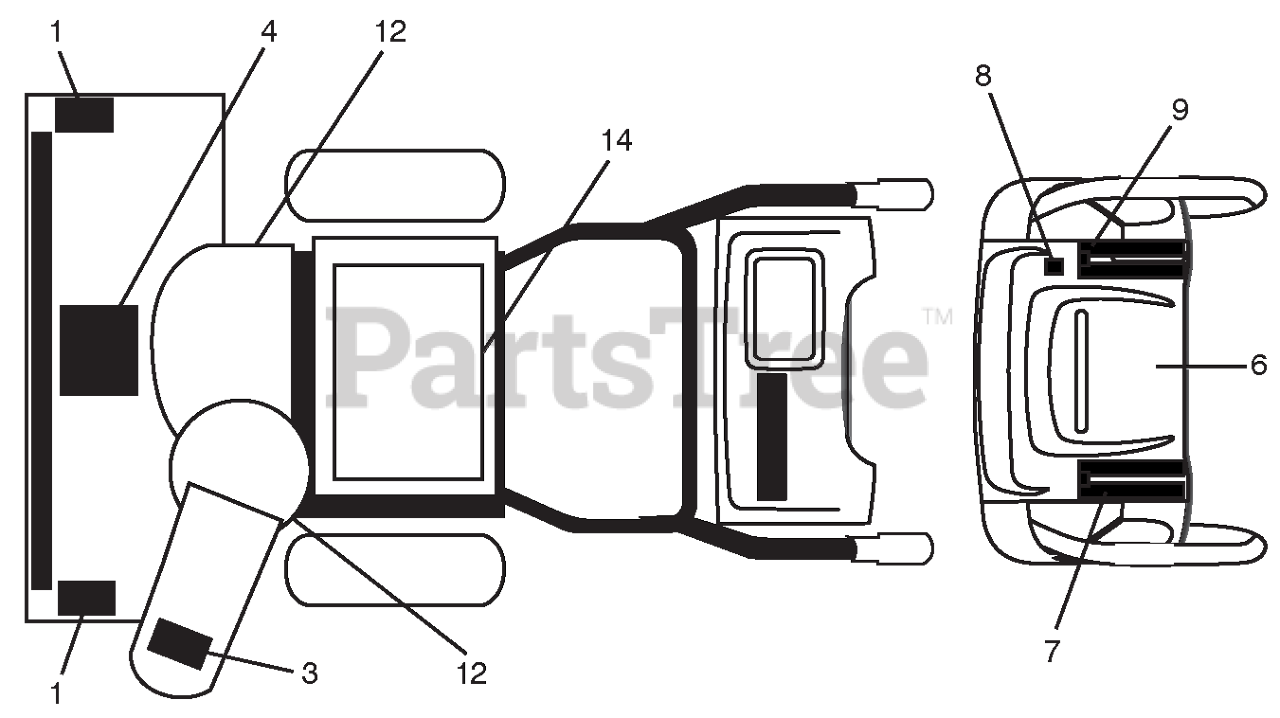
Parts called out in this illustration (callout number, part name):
1	DECAL.AUGER.SAFETY.
3	DECAL.CHUTE.SAFETY.
4	DECAL.AUGER."
7	DECAL.CONS.LT.SPD/LEV/PWRST.
8	DECAL.CONSOLE.HAND.WARMER
9	DECAL.CONS.RT.SPD/LEV/PWRST.
12	DECAL.BELT.GUARD.
14	DECAL.FENDER
